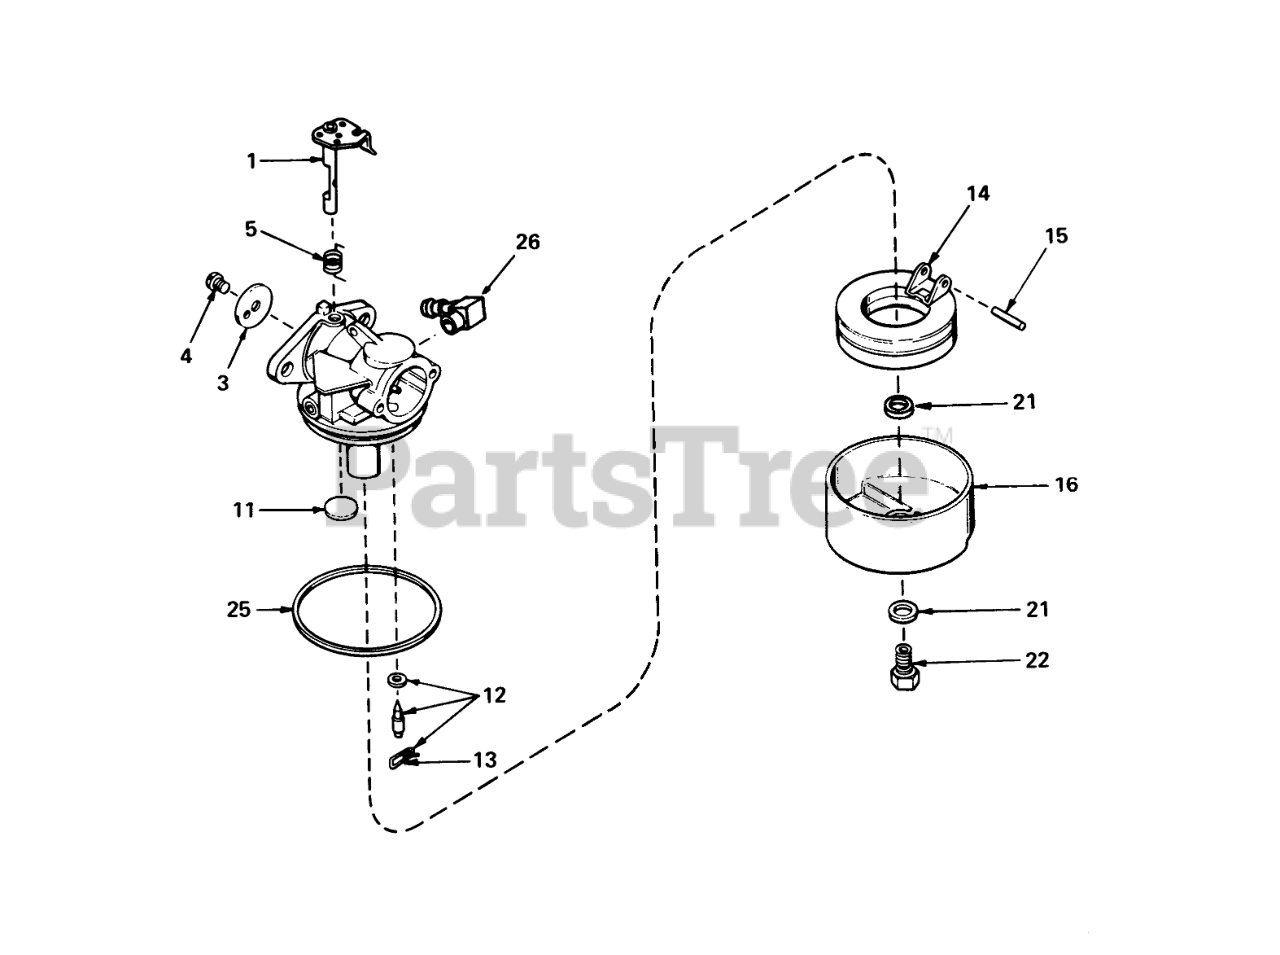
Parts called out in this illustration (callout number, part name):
1	Throttle Shaft and Lever ASM
3	Throttle-Shutter
4	Screw-Shutter
5	Spring, Return
11	Plug-Welch, Atmospheric Vent
12	Inlet Needle, Seat & Clip Assy. (Incl. No. 13)
13	Clip-Spring
14	Float,Carburetor
15	Shaft-Float
16	Bowl Float
21	Gasket-Bowl
22	Nut-Float Bowl
25	O Ring-Bowl, Float
26	Fitting-Fuel
